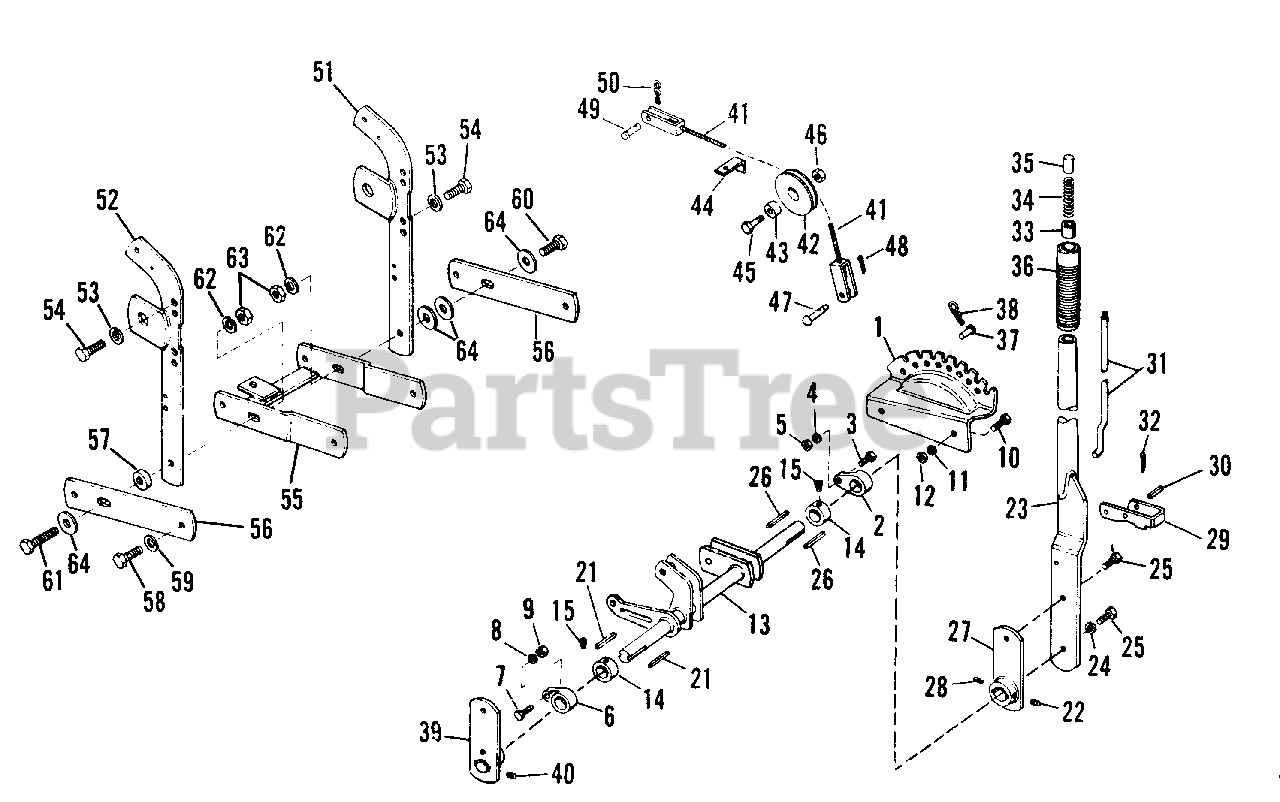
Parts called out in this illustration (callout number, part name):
1	Lift Lever Quadrant
2	Lift Lever Bearing
3	Hex Cap Screw. 5/16"-18 x 1-1/4"
4	Lock Washer, 5/16"
5	Full Hex Nut. 5/16"
6	Lift Lever Bearing
7	Hex Cap Screw, 5/16"-18 x 1-1/4"
8	Lock Washer 5/16"
9	Hex Nut, 5/16"-18
10	Hex Cap Screw, 3/8"-16 x 3/4"
11	Lock Washer 3/8"
12	Full Hex Nut, 3/8"
13	Lift Shaft Assy.
14	Set Collar
15	Set Screw Sq. Hd., 5/16"-18 x 3/8"
17	Set Collar
19	Set Screw, 5/16"-18 x 3/8"
20	Set Screw
22	Set Screw, 5/16"-18 x 1/4"
23	Lift Lever Assy.
24	Lock Washer, 3/8"
25	Hex Cap Screw, 3/8"-16 x 1"
27	Lift Lever Assy, Inner Section
28	Set Screw 5/16"-18 x 1/4"
29	Lift Lever Latch
30	Roll Pin, 3/8" x 1-1/4"
31	Latch Rod
32	Cotter Pin, 3/32" x 3/4"
35	Thumb Button
36	Handle Grip
38	Spring Clip
39	Front Lift Lever Assy.
40	Set Screw, 5/16"-18 x 1/4"
41	Cable Assy., Lift
44	Cable Guard
46	Hex Jam Lock Nut, 3/8"-16
47	Pin
48	Cotter Pin, 3/32" x 7/8"
50	Spring Clip
51	Arm Assembly
52	Arm Assembly
53	Lock Washer, 7/16"
54	Hex Cap Screw, 7/16"-14 x 1"
55	Draw Bar Assembly
58	Hex Cap Screw, 7/16"-14 x 1-1/4"
59	Lock Washer, 7/16"
60	Hex Cap Screw, 7/16"-14 x 1-1/2"
61	Hex Cap Screw, 7/16"-14 x 3/4"
62	Lock Washer, 7/16"
63	Full Hex Nut, 7/16"-14
64	Plain Washer, 5/16"
